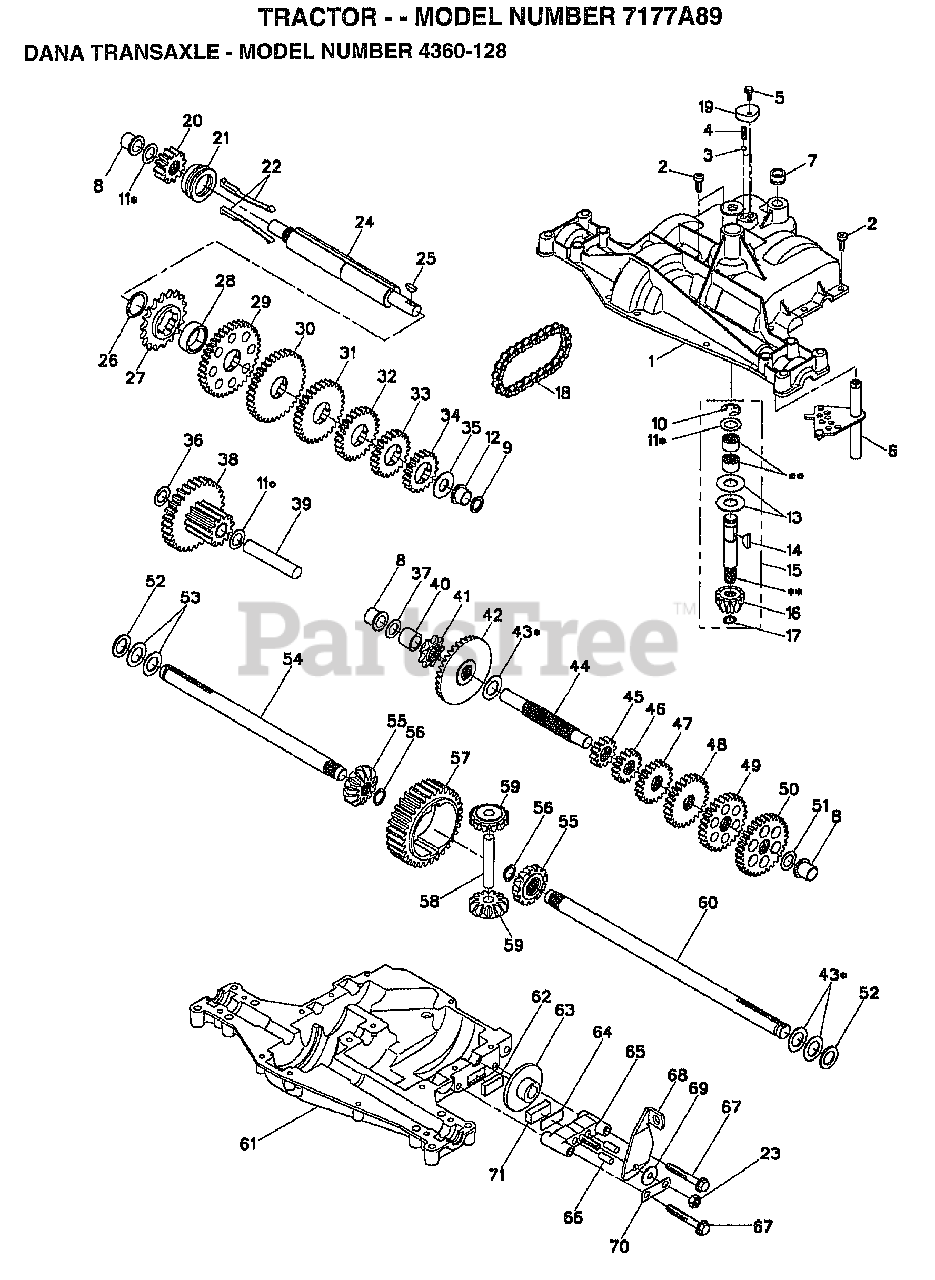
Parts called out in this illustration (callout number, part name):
1	HOUSING.UPPER(5305-P)
4	"SPRING, DETENT LT"
5	SCREW.TAPPING.1/4-20X.734
6	KIT SHIFTER ASM
9	SEAL.OIL.DAN.5508
10	RETAINING RING LT
11	ASM KIT SHIM 4689
12	BEARING.FLNG.5511
13	WASHER T
14	KEY WOODRUFF-DANA
15	INPUT SHAFT KIT 6250
16	PINION.BEVEL.12T(5620)
17	"RING,RETAINING LT"
18	"CHAIN,24 PTCH LT"
19	COVER.DETENT.(5584)
20	GEAR.SPUR.12T.(5627)
21	CLUTCH.COL.5467
22	ASM KIT CLTCH KEY
23	NUT.LOCK.5/16-24
24	SHAFT INTERM DANA
25	WOODRUFF KEY
26	"RING,RETAINING LT"
27	SPROCKET 18T T
28	SPACER YT
29	GEAR SPUR 37 TTH
30	GEAR SPUR 35 TTH
31	GEAR SPUR 30T
32	GEAR 25T LT
33	GEAR SPUR 22 TT
34	SPUR GEAR 19T
35	"WASHER, PLAIN LT"
36	WASHER 045
37	WASHER 031
38	ASSY.GEAR.6153 12T&30T
39	SHAFT IDLER
40	SPACER T
41	SPROCKET 9T LT
42	GEAR.BEVEL.36T(5621)
43	ASM KIT SHIM
44	SHAFT T
45	GEAR SPUR 12 TTH
47	GEAR SPUR 20T
48	"GEAR, SPUR 25T LT"
49	GEAR 28T T
50	"GEAR, SPUR 31T LT"
51	WASHER 060
52	NEOPRENE WASHER
53	WASHER 031
54	AXLE.LH(5528-1)
55	MITER 5270 12T.SPLINED
56	RING.RETAINING.(5270)
58	SHAFT T
59	MITER 5623.12T.IDLER
60	AXLE.RH.(5528-2) DANA
61	HOUSING.KIT (6088)
62	PUCK T
63	BRAKE DISC. T
64	SPACER LT
66	PIN T
67	SCREW.(5562) .5/16-18X2.35
69	WASHER LT
70	BRACKET, ANTI-ROTATION
71	PUCK T
